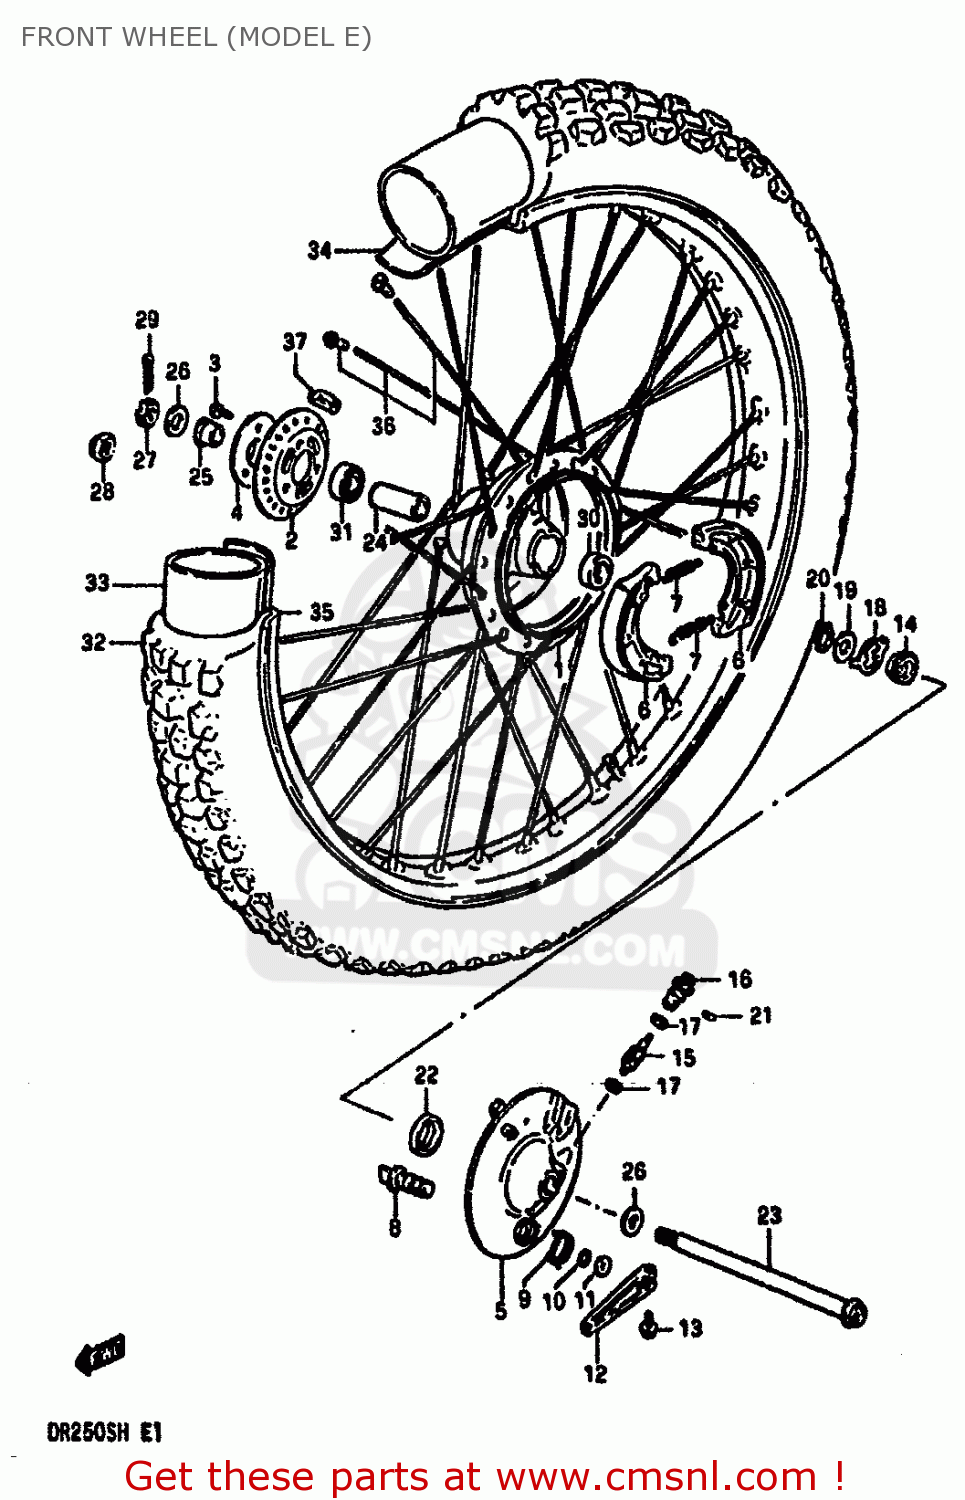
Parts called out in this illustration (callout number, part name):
1	DRUM,FRONT HUB
2	FLANGE,FR HUB,R
3	BOLT
4	PLATE,FRONT HUB BEARING
5	PANEL,FRONT HUB
6	SHOE,BRAKE (NAS)
7	SPRING(L:34)
8	CAM,BRAKE
9	SPRING
10	O-RING (D:2.4 ID:13.8)
11	WASHER (14.5X22X1.6)
12	LEVER,FRONT BRAKE CAM
13	BOLT
14	GEAR,SPEEDOMETER
15	PINION,SPEEDOMETER
16	BUSH,METER GEAR OUTER
17	WASHER (5.1X9X0.4)
18	DRIVER,SPEEDOMETER GEAR
19	WASHER(18.5X24X1)
20	CIRCLIP
21	SCREW
22	OIL SEAL (43X58X7)
23	AXLE,REAR
24	SPACER (12.6X19X52)
25	SPACER (12.2X19X18.5)
26	WASHER
27	NUT, REAR AXLE
28	NUT 12MM
29	COTTER PIN
30	BEARING
31	BEARING, RH
32	TIRE,FRONT
33	TUBE
34	PROTECTOR,WHEEL,INNER
35	RIM,FRONT WHEEL (1.60X21)(
36	SPOKE SET,FRONT
37	BALANCER,WHEEL (50G)
